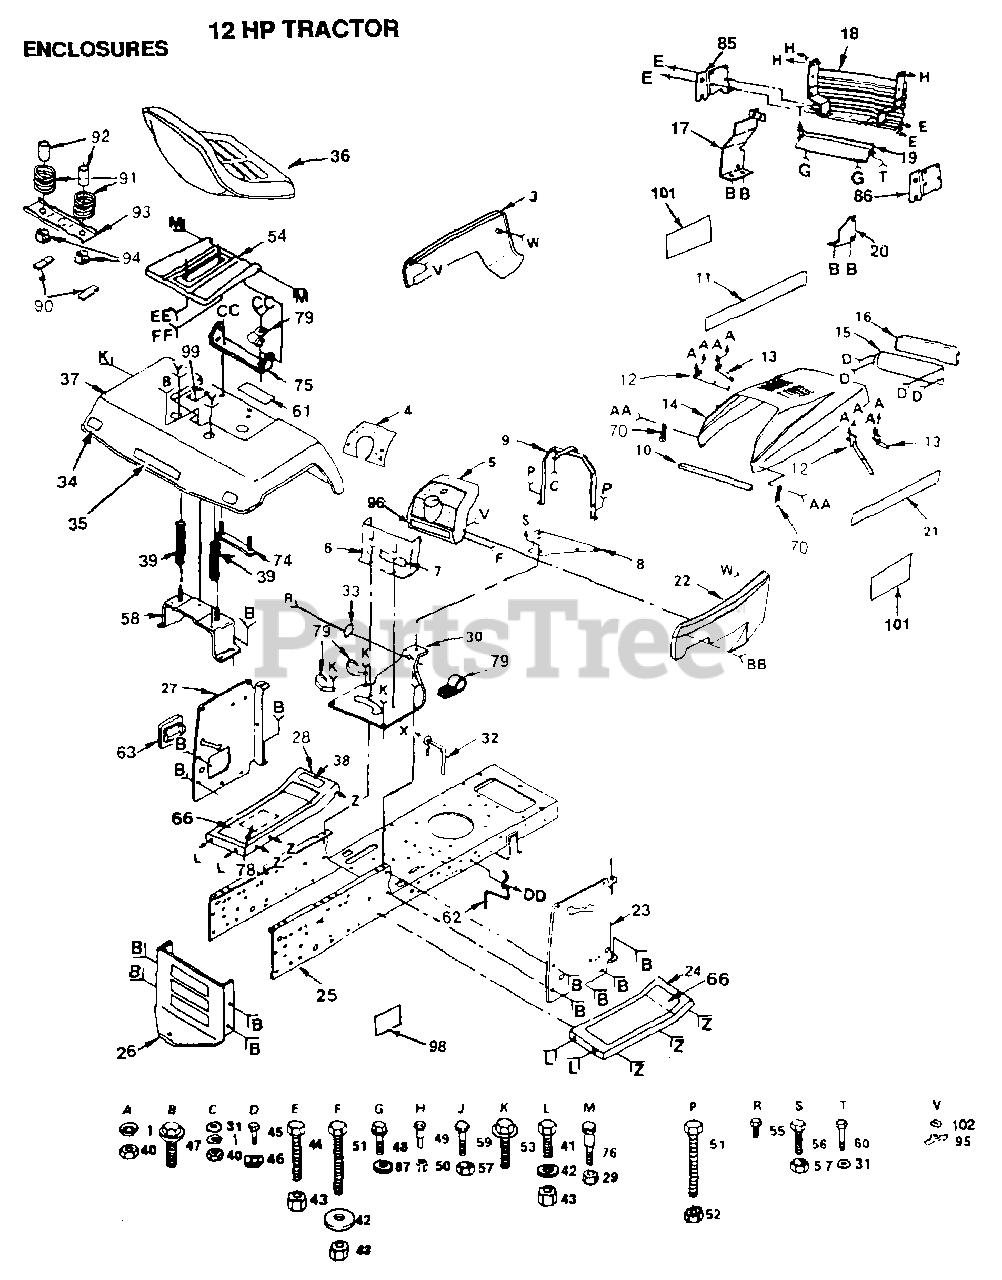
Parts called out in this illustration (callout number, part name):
6	DASH ASSY LT
9	SUPPORT ASSY LT
10	FOAM-STRIP LT
11	DECAL HOOD LH
16	LENS LT
20	SUPPORT LH YTH
23	PANEL DASH RH YT
28	FOOTREST LH YT
31	WASHER PM
32	BELT GUIDE
34	REFLECTOR-TAIL YT
38	DECAL T
39	SPRING COMPRESSIO
42	WASHER
44	BOLT
46	"""J"" FASTENER LT"
47	SCREW
48	SCREW
49	BOLT T
52	NUT
53	SCREW LT
56	BOLT
59	SCREW
60	SCREW HEX CRT
61	DECAL
62	BELT GUIDE
63	COVER ACCESS
70	HOOD LATCH T
79	CLIP T
85	SUPPORT LH YTH
86	SUPPORT RH YTH
87	WASHER
90	STRIP FORM
91	SPRING
92	SPACER SPLIT
93	BRKT SWITCH
94	BUSHING
101	DECAL.HOOD.LOGO.
102	LOCKWASHER GT
